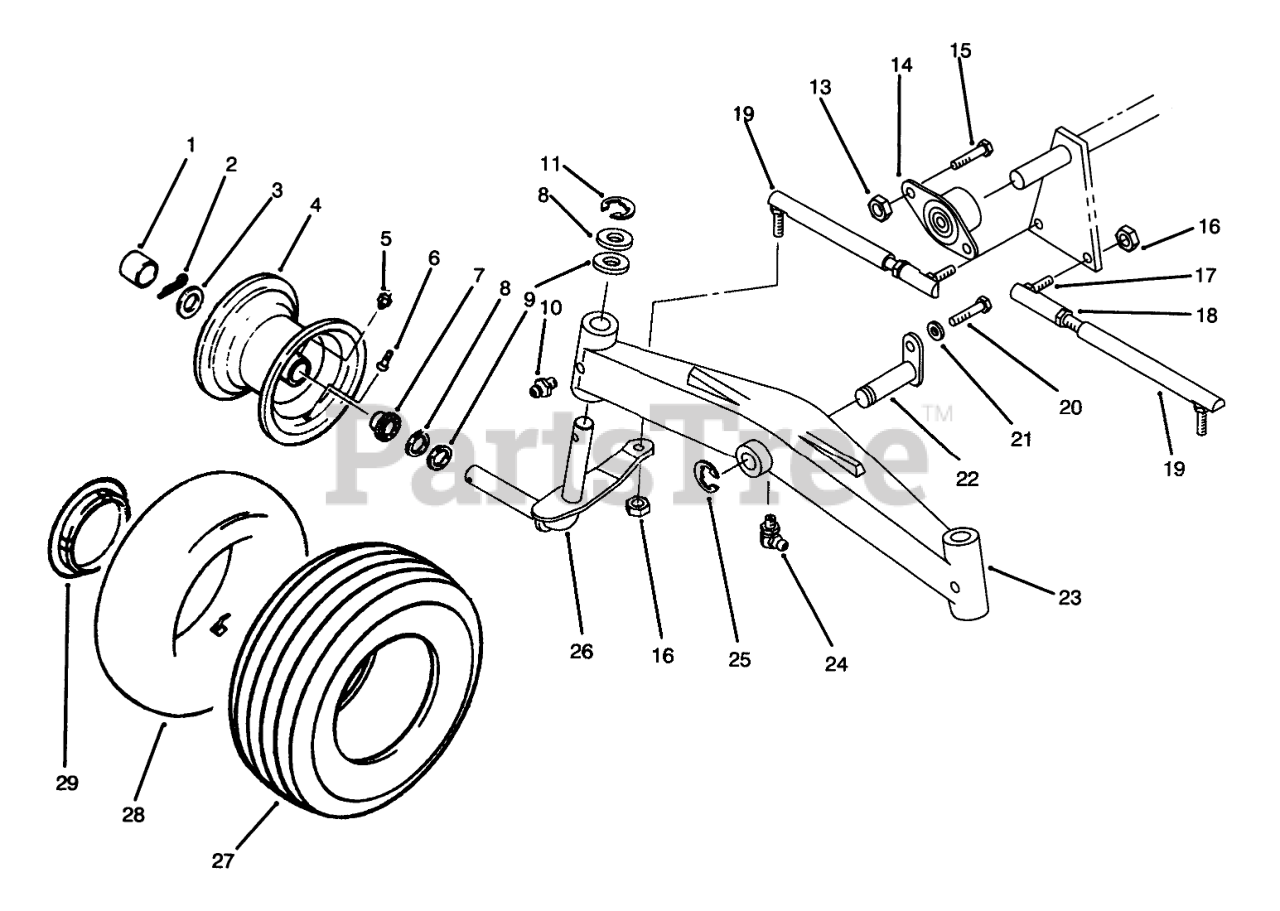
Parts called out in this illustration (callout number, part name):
1	HUBCAP
2	PIN-COTTER
3	WASHER WHEEL
4	Assembly-Wheel (Incl. Ref. #5-7)
5	ZERK-GREASE
6	VALVE
7	BEARING-WHEEL
8	WASHER
9	WASHER-SHIM
10	FITTING-GREASE
11	RING-RETAINING
13	NUT-LOCK, NI
14	BEARING-FLANGED
15	SCREW-HH
16	NUT-LOCK
17	BALL-JOINT
18	NUT-HEX
19	Assembly-Tie Rod (Incl.Ref.#17&18)
20	SCREW-HH
21	WASHER-LOCK
22	PIN AND PLATE ASM
23	AXLE-FRONT
24	FITTING-GREASE
25	E-RING
26	RH SPINDLE WA
27	Tire (16 x 6.5-8) 2-Ply -2 Wheel Axel
29	8"-HUB CAP LOGO
